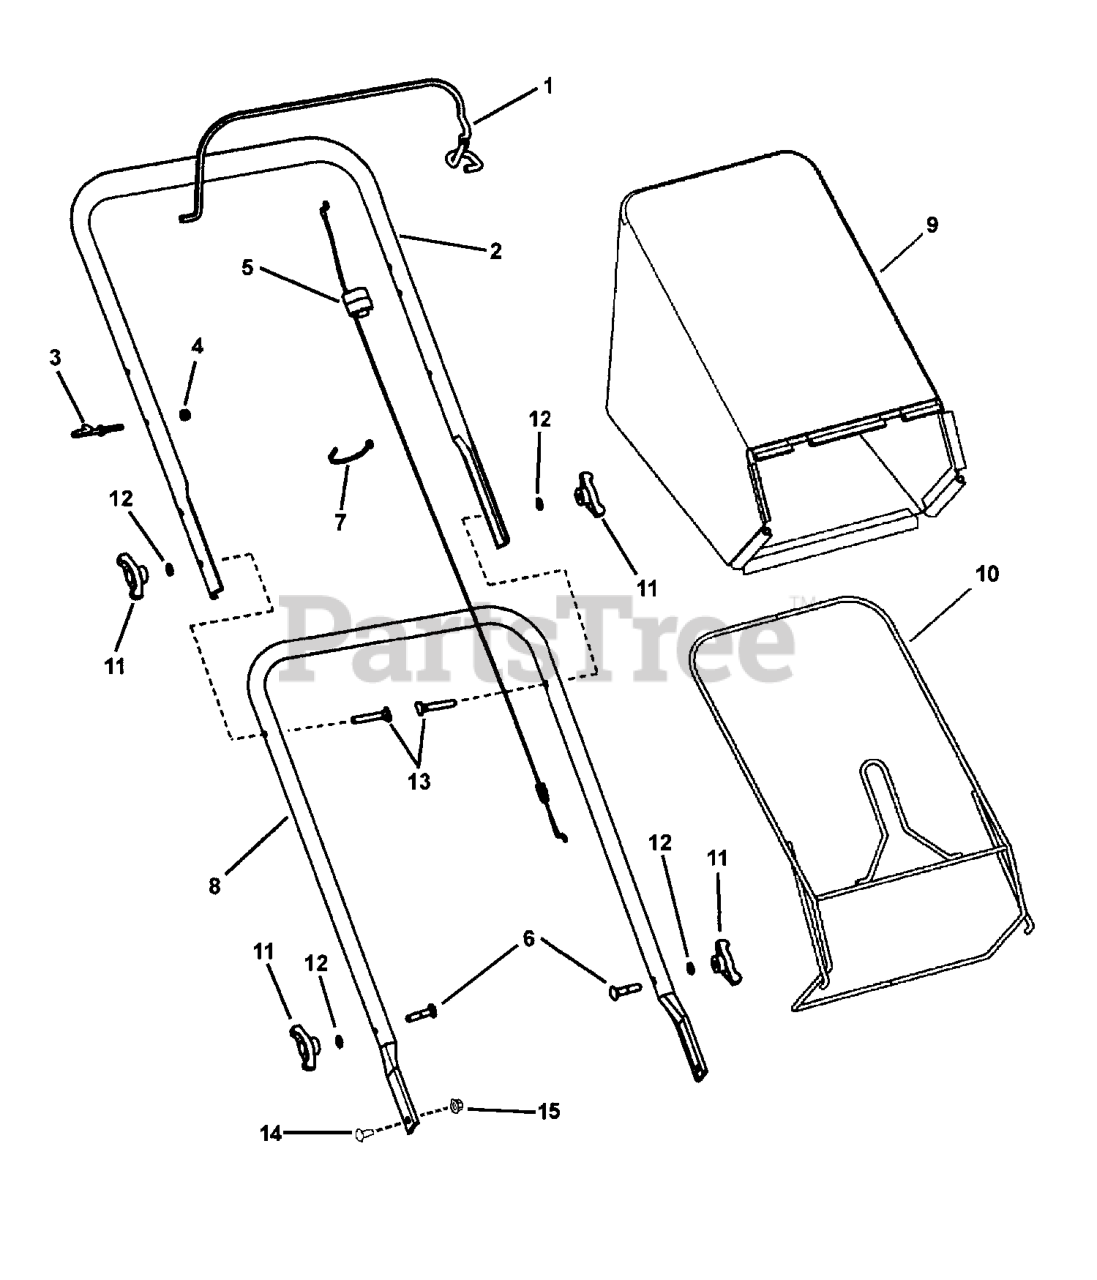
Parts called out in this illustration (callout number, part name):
1	BAIL, OPC Push
2	HANDLE, Upper
3	GUIDE, Rope - 1/4-20 thread
4	NUT, 1/4-20 Nyloc
5	CABLE, Bail, 22" WBM, - 41-1/2
6	BOLT, Carriage, 5/16-18 x 1, GR 5
7	WIRE TIE, 11 Inch Std Black Nylon
8	HANDLE, Lower
9	BAG, Cloth, Grass Bag
10	FRAME, Grass Bag
11	KNOB, Wing, 5/16-18
12	WASHER, Internal Tooth Lock, 5/16
13	BOLT, Carriage, 5/16-18 x 2, GR 2
14	BOLT, Carriage 5/16-18 x .75
15	NUT, Hex Flange, Center Lock, 5/16-18
